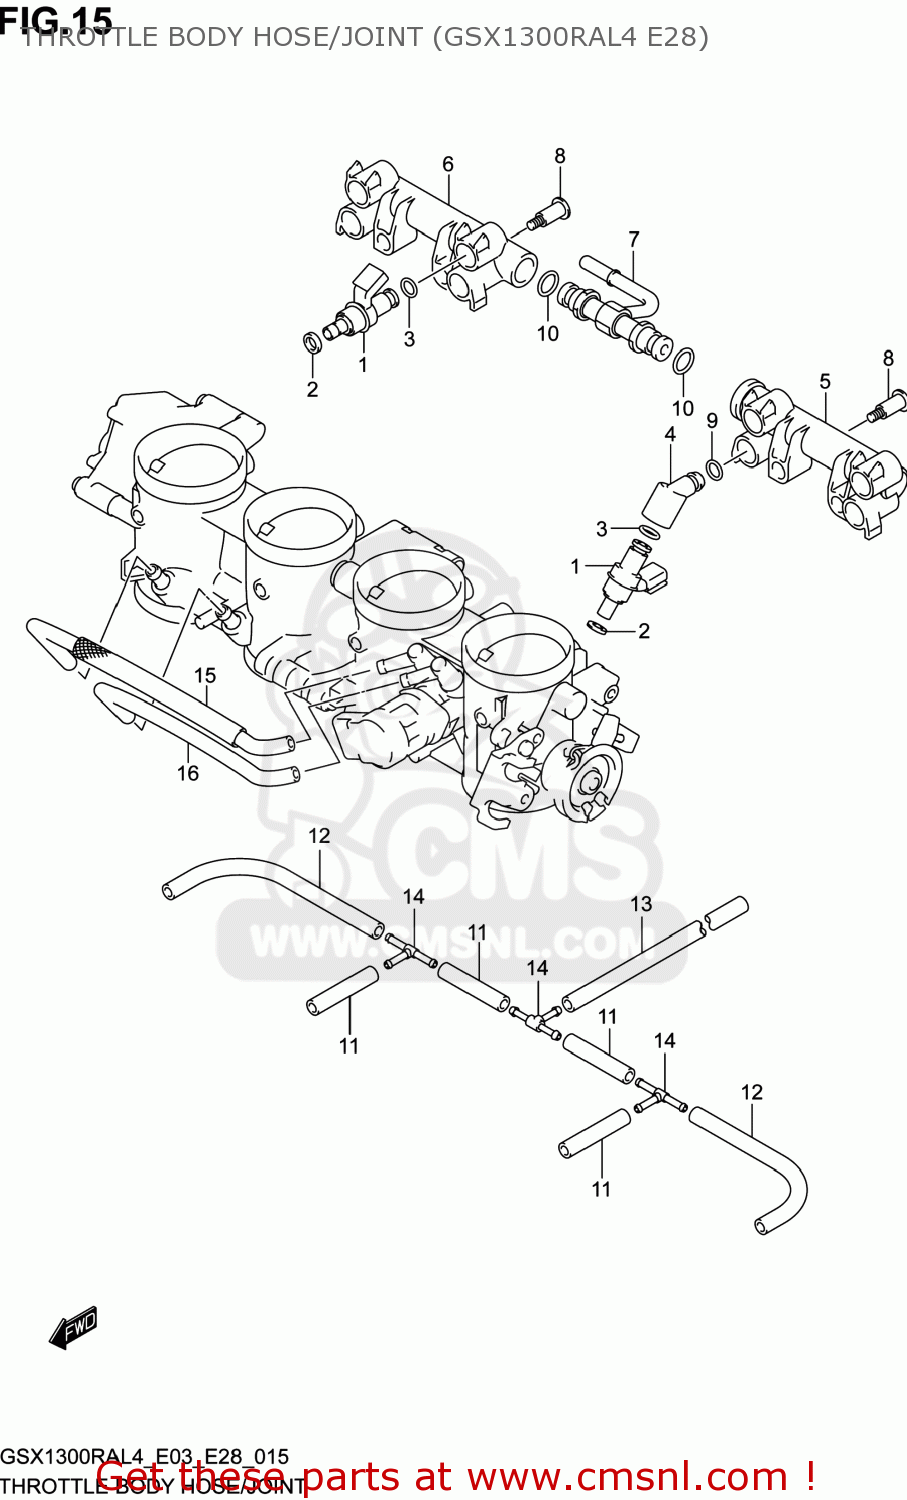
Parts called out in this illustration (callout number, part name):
1	INJECTOR ASSY
2	RING,SEAL
3	O RING
4	PIPE,FUEL
5	PIPE,FUEL
6	PIPE,FUEL
7	JOINT
8	SCREW
9	O RING
10	O RING
11	HOSE,RUBBER(L:35)
12	HOSE,RUBBER(L:100)
13	HOSE,RUBBER(3X7X170)
14	JOINT
15	TUBE
16	TUBE
